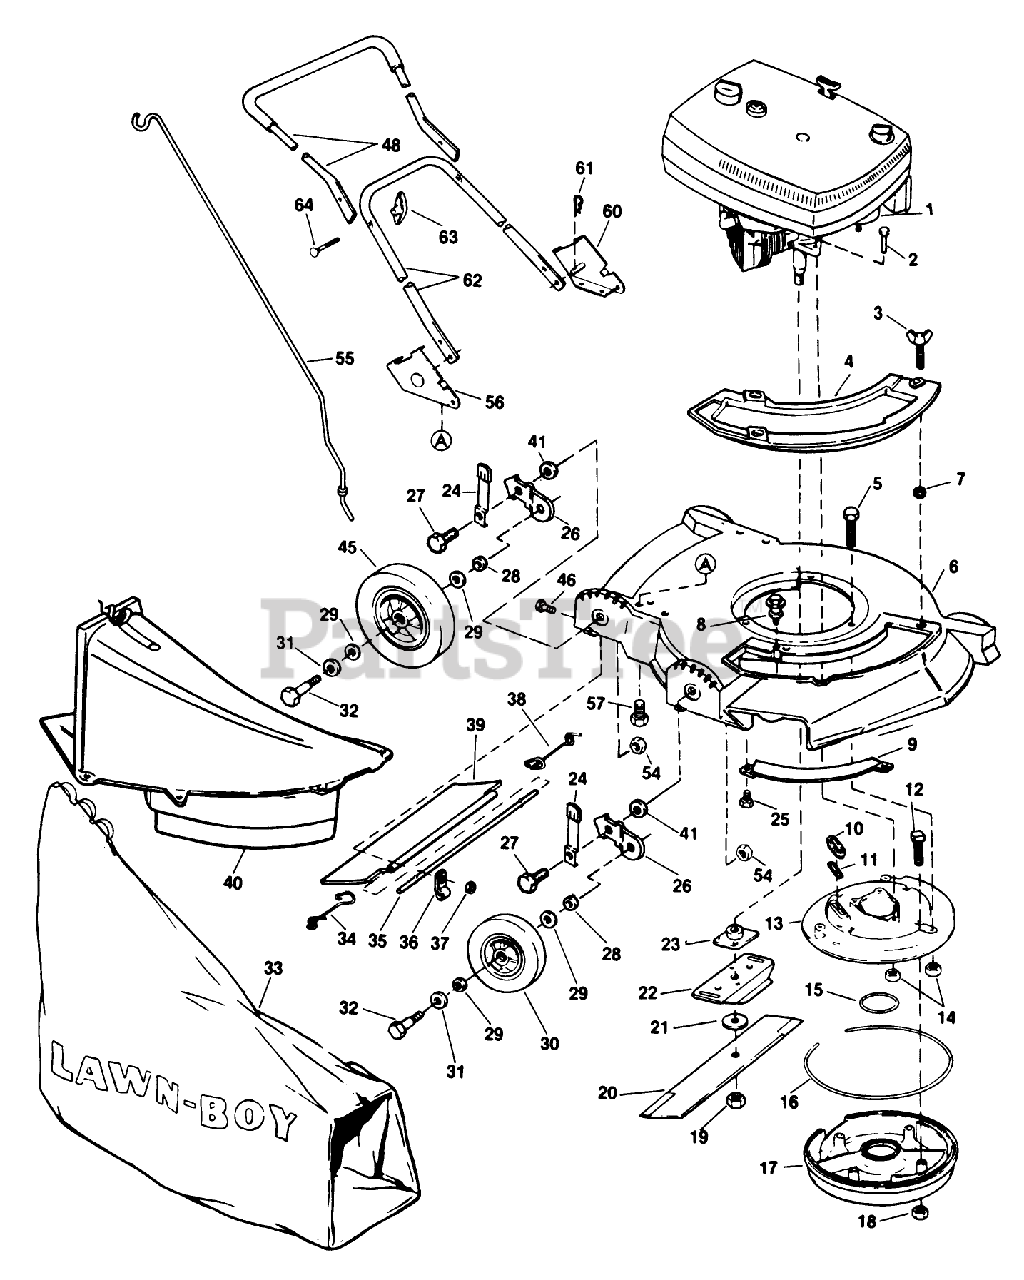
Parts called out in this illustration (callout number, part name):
1	See Note #2 at bottom of this page.
3	WING SCREW LAWRE
5	SCREW V
9	TOE BAR 19"
9	BAR-TOE
11	GASKET S
14	NUT-LOCK F
16	Gasket Muffler (outside)
18	LOCKNUT E
19	NUT-BLADE
21	WASHER
23	PLATE AND COLLAR ASM
28	WASHER WROUGHT
30	WHEEL & TIRE KIT
32	BOLT WHEEL
33	ORD LB 89802 WHOLE GOODS
34	SPRING;TRAILING SHIELD RH
35	ROD T/SHIELD ADV WIRE
35	ROD 21" ADVANCE
36	CLAMP ROD KMC
37	LOCKNUT E
38	SPRIG T/SHLD ASOC
54	LOCKNUT
55	ROD GRASSBAG
57	SCREW
61	HAIR PIN
62	DISC SEE NOTES
63	NUT-WING
